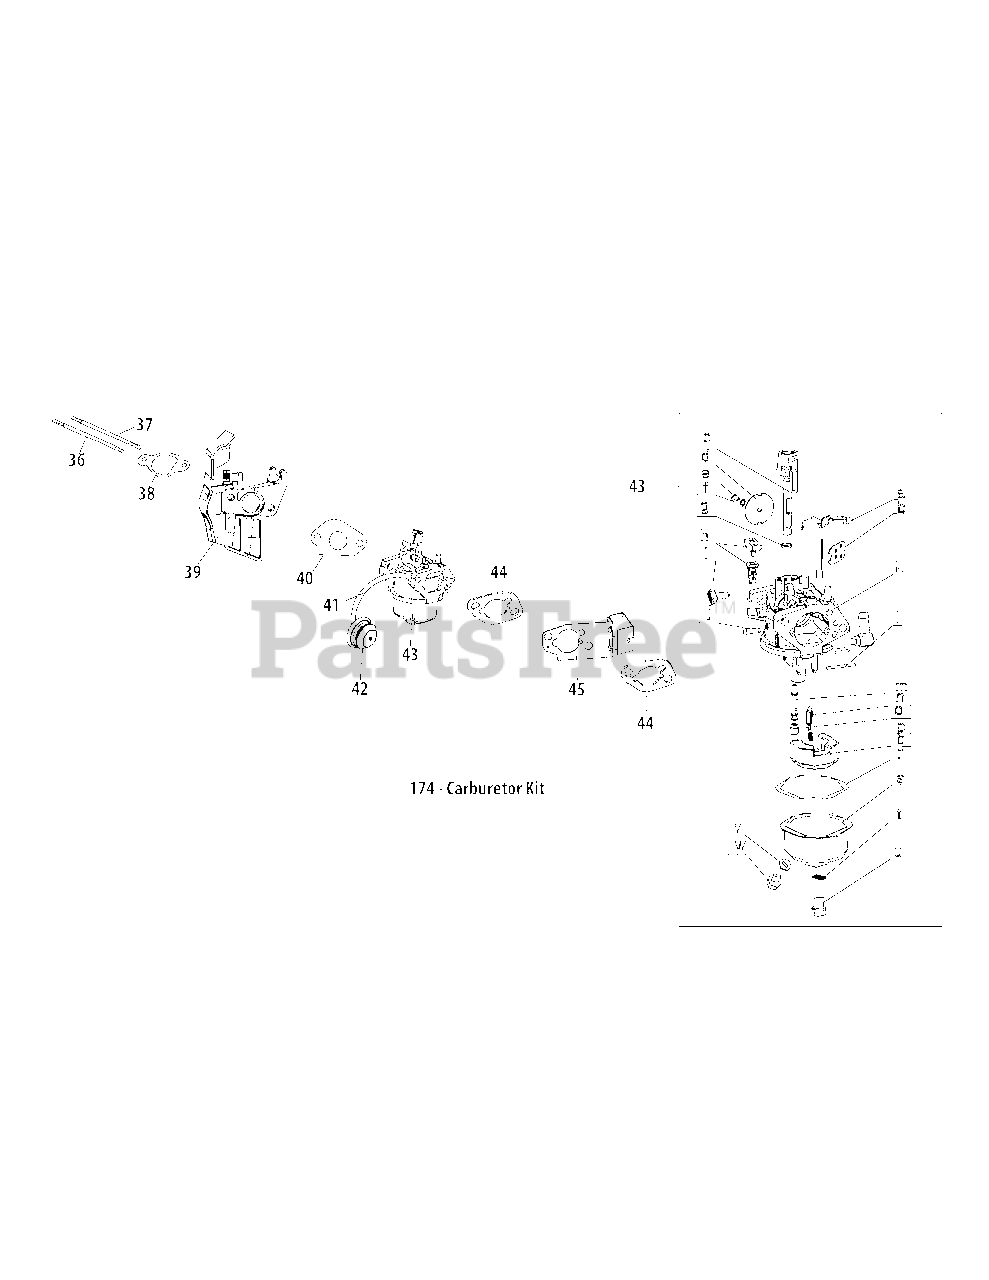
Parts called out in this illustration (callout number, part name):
36	Stud M6×117
37	Stud M6×105
38	Carburetor Insulator Gasket
39	Carburetor Insulator
40	Carburetor Gasket
41	Primer Hose
42	Primer Assembly
43	Carburetor Assembly
44	Carburetor Gasket Plate
45	Choke Control
174	Carburetor Kit
